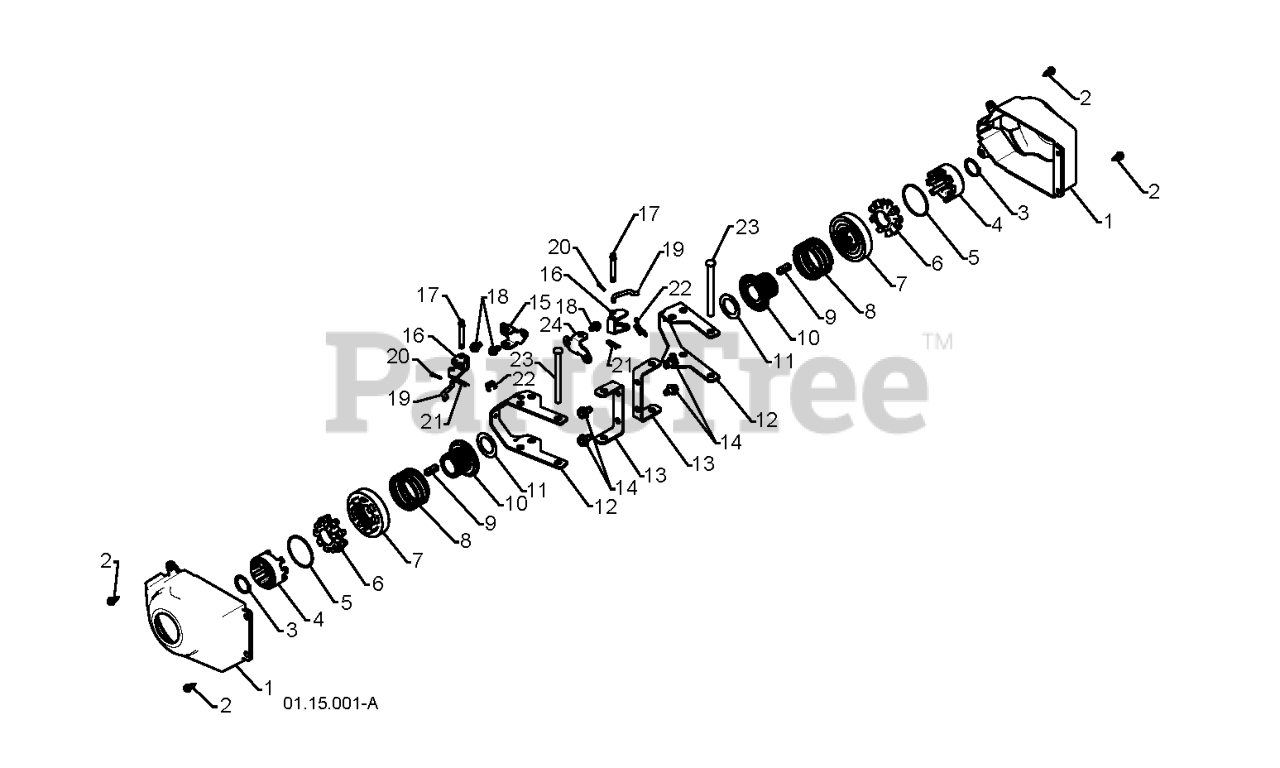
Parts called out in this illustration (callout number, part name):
1	COVER, POWER STEERING
2	SCREW, HEX HEAD, TAPPING
4	RP.DRIVER WHEEL
5	RING, WIRE RETAINER
6	LOBE WHEEL
7	RP.SLIDE.CLUTCH
8	SPRING, CLUTCH SLIDE
9	KEY, SQUARE 1/4 X .875
10	RP.LOBE.AXLE
11	WASHER TRUST 1"
12	YOKE.PNT.WELDMENT.STEE
13	BRACKET
14	Screw 5/16-18 x 1/2 Hex, Self Tapping 5/16-18 x 1/2
15	BRKT.STEER.PIVOT.RH
16	BELLCRANK.STEER
17	PIN, STEERING BELLCRANK
18	SCREW 1/4X20
19	LINK.STEER.YOKE
20	RETAINER CLIP
21	RETAINER CLIP PM
22	SPRING LATCH
23	PIN, STEERING LEVER
24	BRACKET.STEER.PIVOT.LH.YZ
